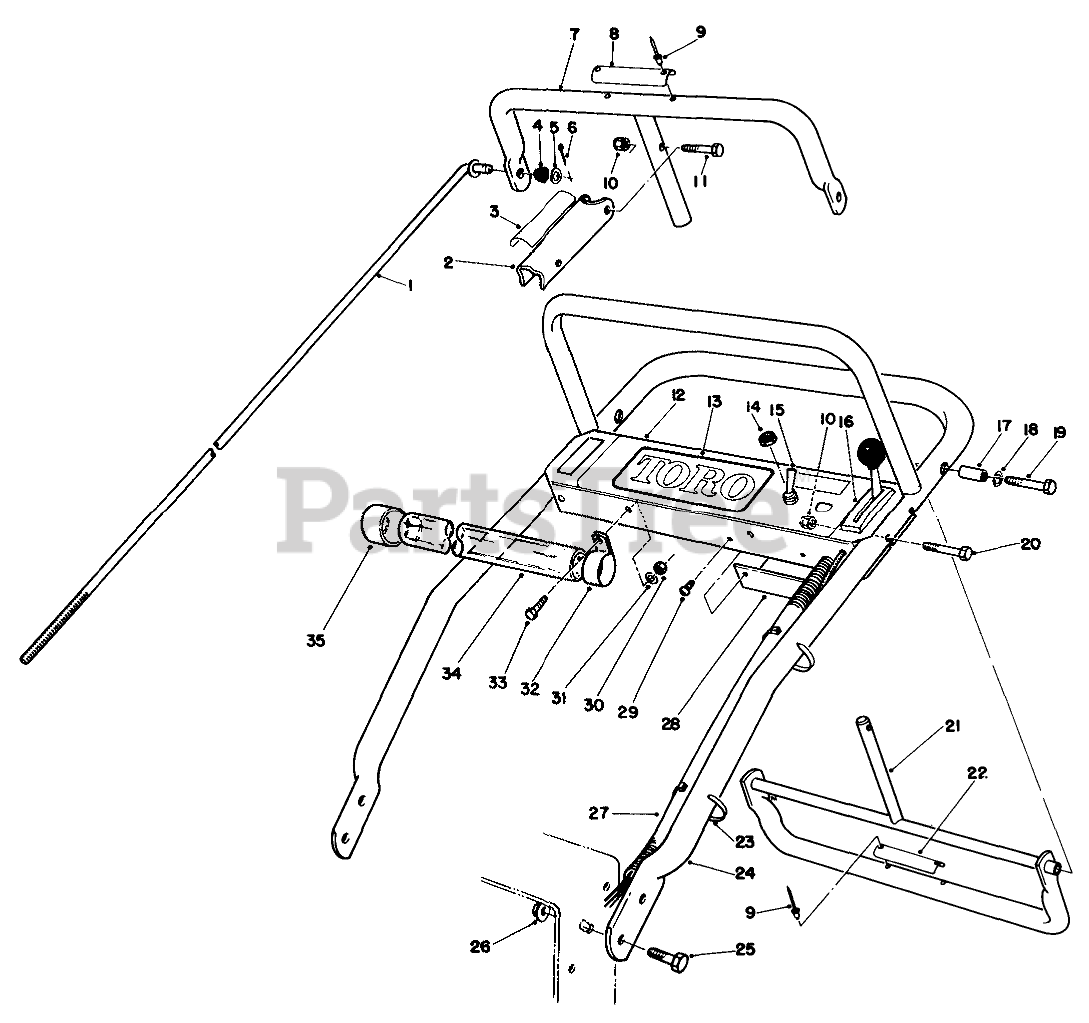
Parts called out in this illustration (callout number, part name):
1	CONTROL ROD B
2	Lever-Parking Brake
3	DECAL-LEVER, PARKING
4	GROMMET-RUBBER
5	WASHER-PLAIN
6	PIN-COTTER
7	Bar-Control
8	DECAL-CONTROL BAR
9	RIVET-BLIND
10	NUT-LOCK, NI
11	SCREW-SHH
12	Panel-Control
13	PANEL DECAL
14	NUT
15	Switch
16	Control-Throttle
17	PIVOT-SPACER
18	WASHER-LOCK
19	SCREW-HH
20	SCREW-SHH
21	Control-Pivot
22	DECAL-REVERSE HANDLE
23	TIE-CABLE
24	Handle-Upper
25	SCREW-HHF
26	NUT-HF
27	WIRE HARNESS
28	PANEL-BOTTOM
29	SCREW-HWHTF
30	NUT-LOCK, NI
31	WASHER-FLAT
32	CLAMP-R
33	SCREW-HH
35	CAP-END
